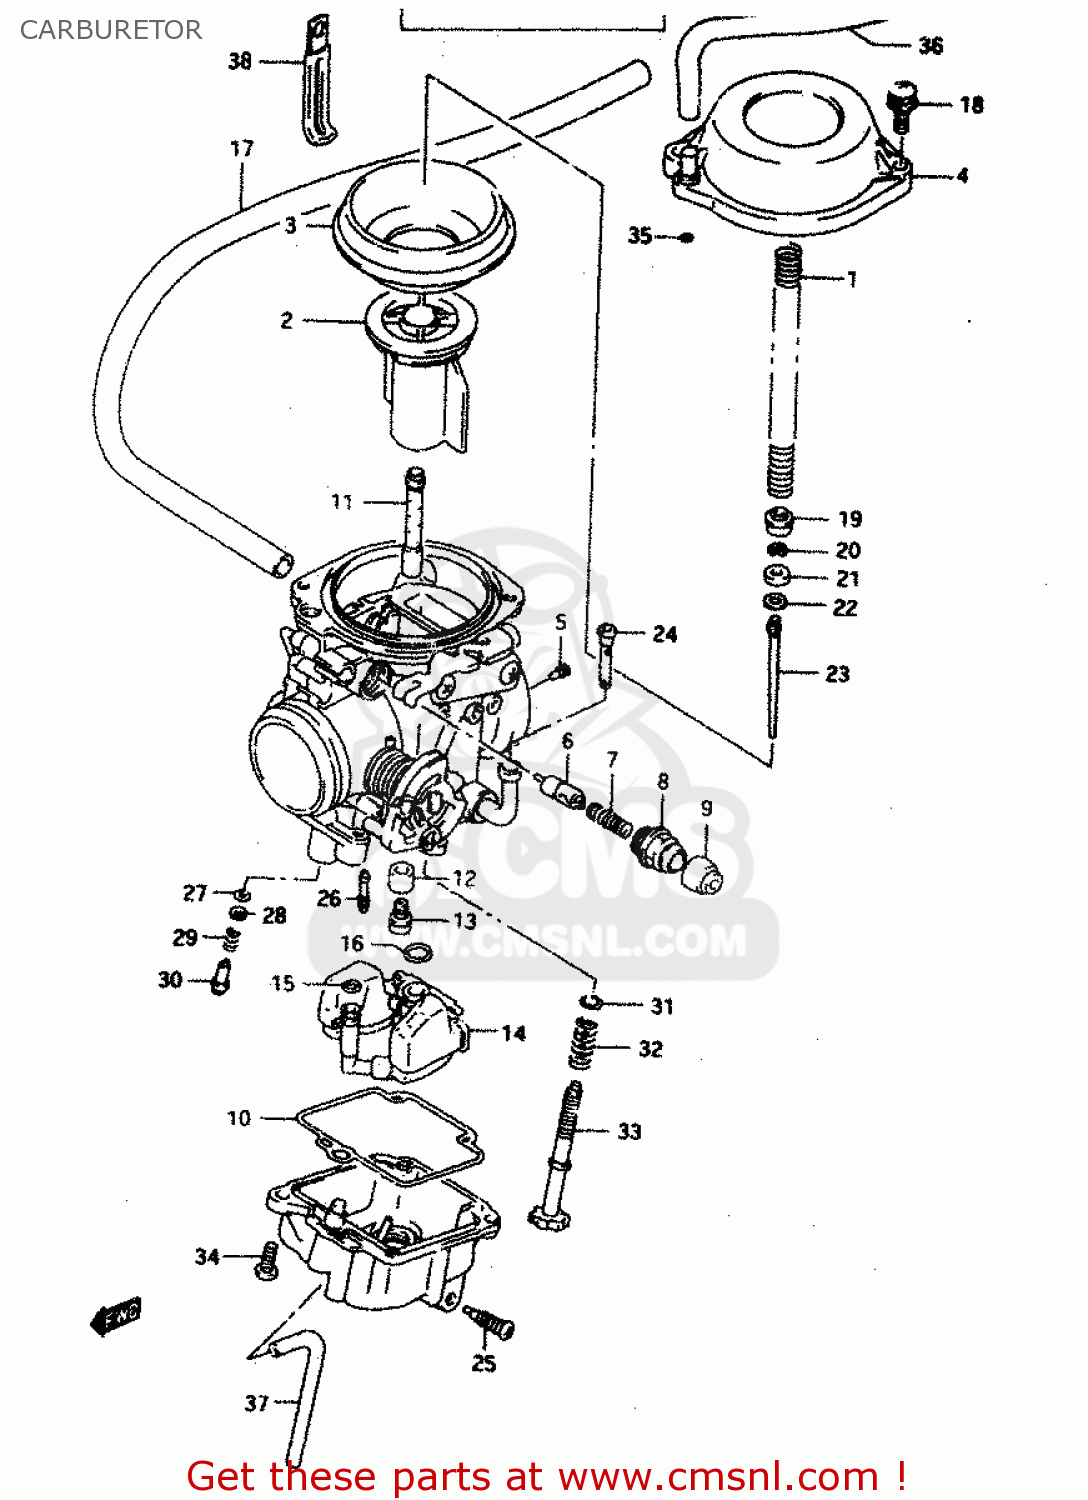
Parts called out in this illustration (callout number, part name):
1	SPRING
2	VALVE,PISTON
3	DIAPHRAGM
4	COVER,DIAPHRAGM
5	JET,AIR
6	PLUNGER
7	SPRING
8	HOLDER,GUIDE
9	CAP
10	GASKET,FLOAT CHAMBER (NAS)
11	JET,NEEDLE(Y-2)
12	RING
13	JET,MAIN(135)
15	O RING
16	O-RING,NEEDLE VALVE
17	HOSE(6.5X11.5X600)
18	SCREW
19	RING
20	CLIP,NEEDLE
21	RING
22	WASHER
23	NEEDLE,JET
24	FILTER
25	SCREW,DRAIN
26	JET,PILOT(52.5)
27	O RING,PILOT AIR SCREW
28	WASHER
29	SPRING
30	SCREW,PILOT
31	WASHER
32	SPRING
33	ADJUSTER
34	SCREW(5X14)
35	O RING
36	HOSE (4.5X8.5X600)
37	HOSE
38	CLAMP
